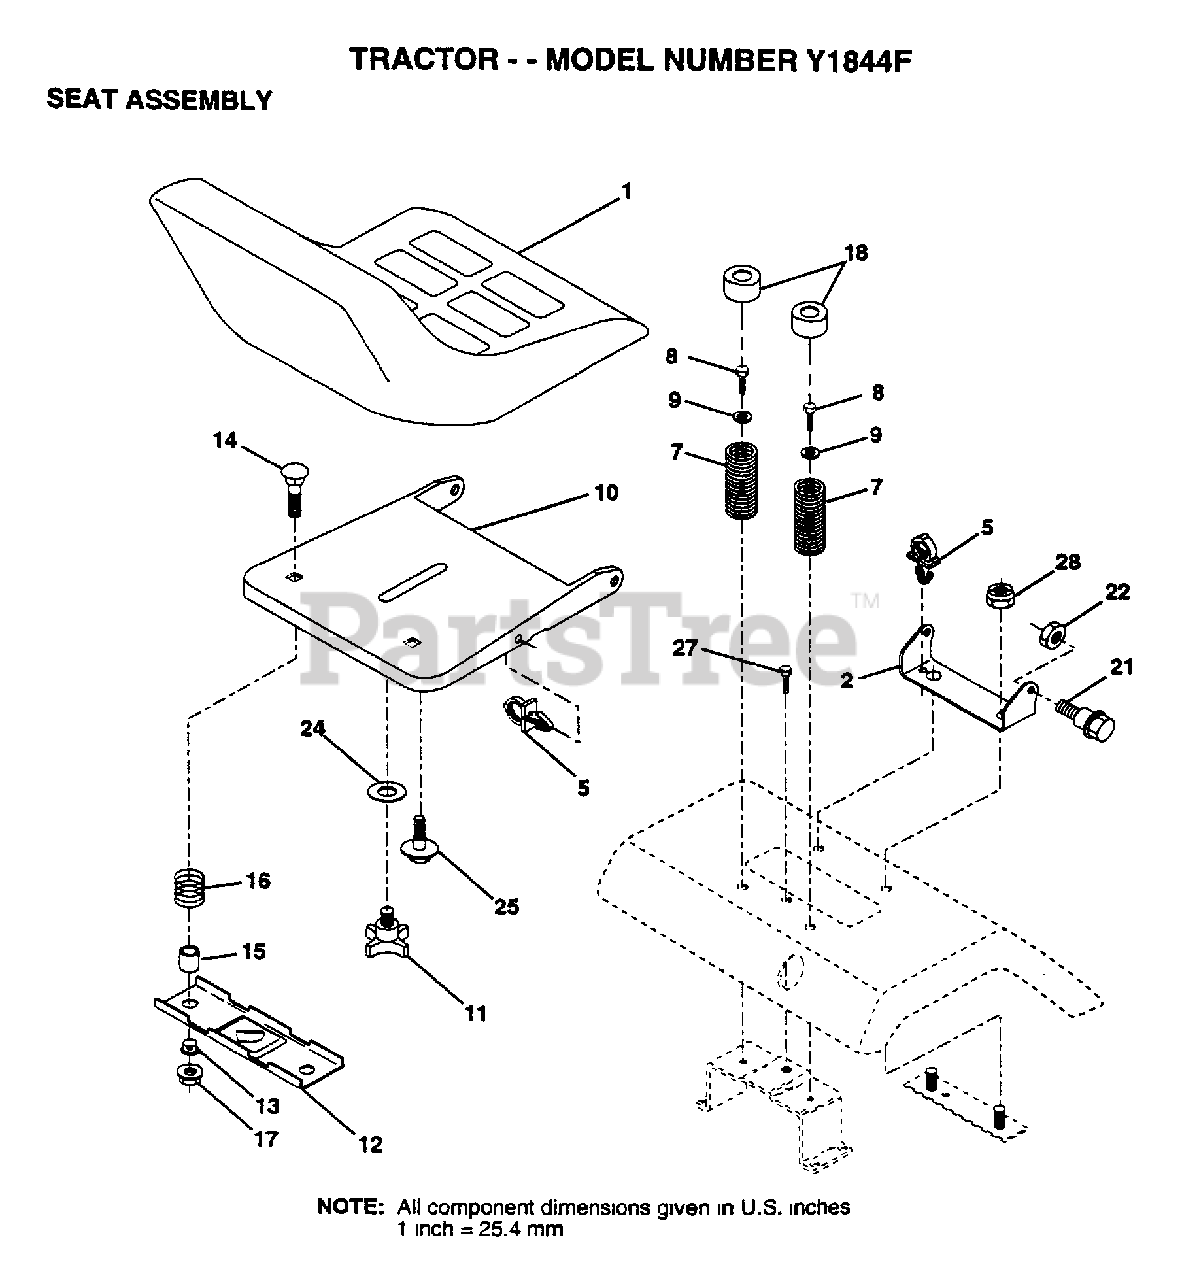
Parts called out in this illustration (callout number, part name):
2	BRACKET PVT SEAT
5	CLIP.PUSH-IN.HING
7	SPRING COMPRESSIO
8	SCREW LT
9	WASHER
11	"KNOB 1/2"" YT"
12	BRKT SWITCH
13	BUSHING
15	SPACER SPLIT
16	SPRING COMPRESSED
18	CAP SPRING
21	BOLT.SHLD.5/16-18
24	WASHER
25	"BOLT,SHOULDER"
27	SCREW LT
